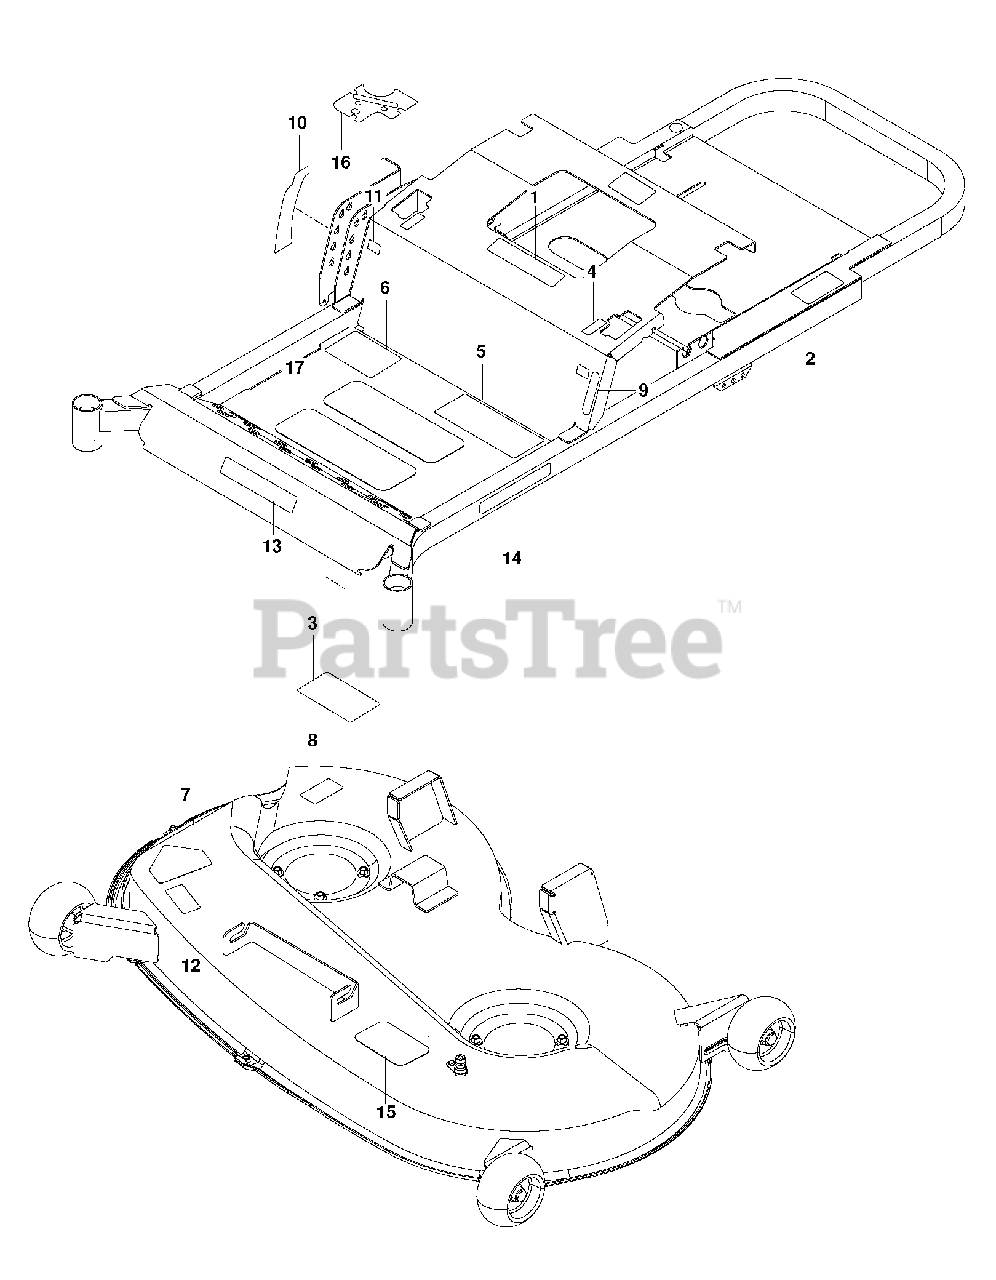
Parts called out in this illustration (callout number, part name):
1	DECAL, BATTERY
2	DECAL, DO NOT MOUNT
3	DECAL, SERVICE
4	DECAL, MOTION CONTROL, BLK
5	DECAL, WARNING
6	DECAL, WARNING
7	DECAL, CPSC
8	DECAL, DANGER
9	DECAL, PARK BRAKE
10	DECAL, HEIGHT
11	DECAL, F.S.T. BLK
12	DECAL, EURO SEVERING
13	DECAL, POULAN, FRONT
14	DECAL, POULAN, LEFT
15	DECAL, BELT ROUTING
16	DECAL, CONTROL PANEL
17	ANTI-SKID PAD
